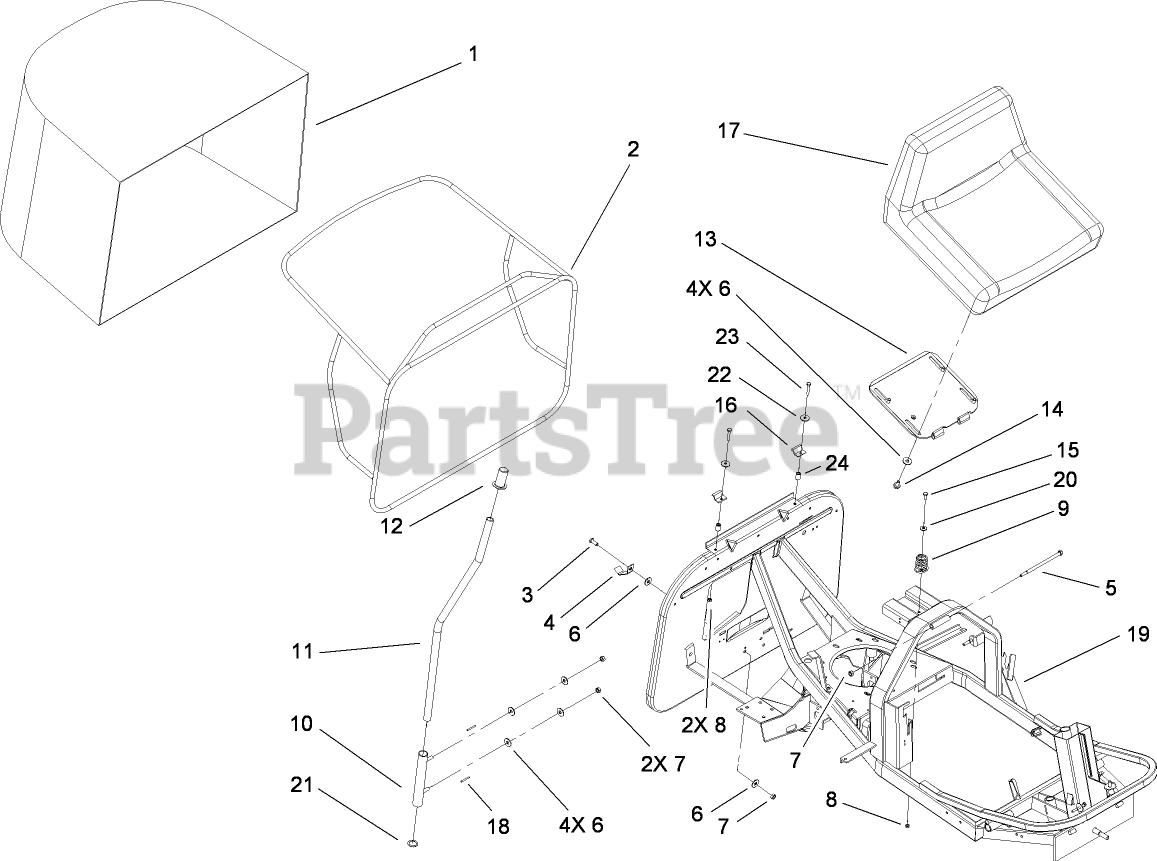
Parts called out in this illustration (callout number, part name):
1	BAG-GRASS
2	FRAME-COLLECTOR
3	SCREW-HH
4	Hook-Bag
6	Washer-Flat
7	NUT-LOCK
9	Spring-Compression
10	Support
11	Lever
13	Plate-Seat
14	SCREW-HHF
15	SCREW-HH
18	Pin-Spring
19	FRAME-COMPLETE
20	Washer-Flat
21	Spacer
22	Washer-Flat
23	SCREW-HH
24	SPACER-COLLECTOR
